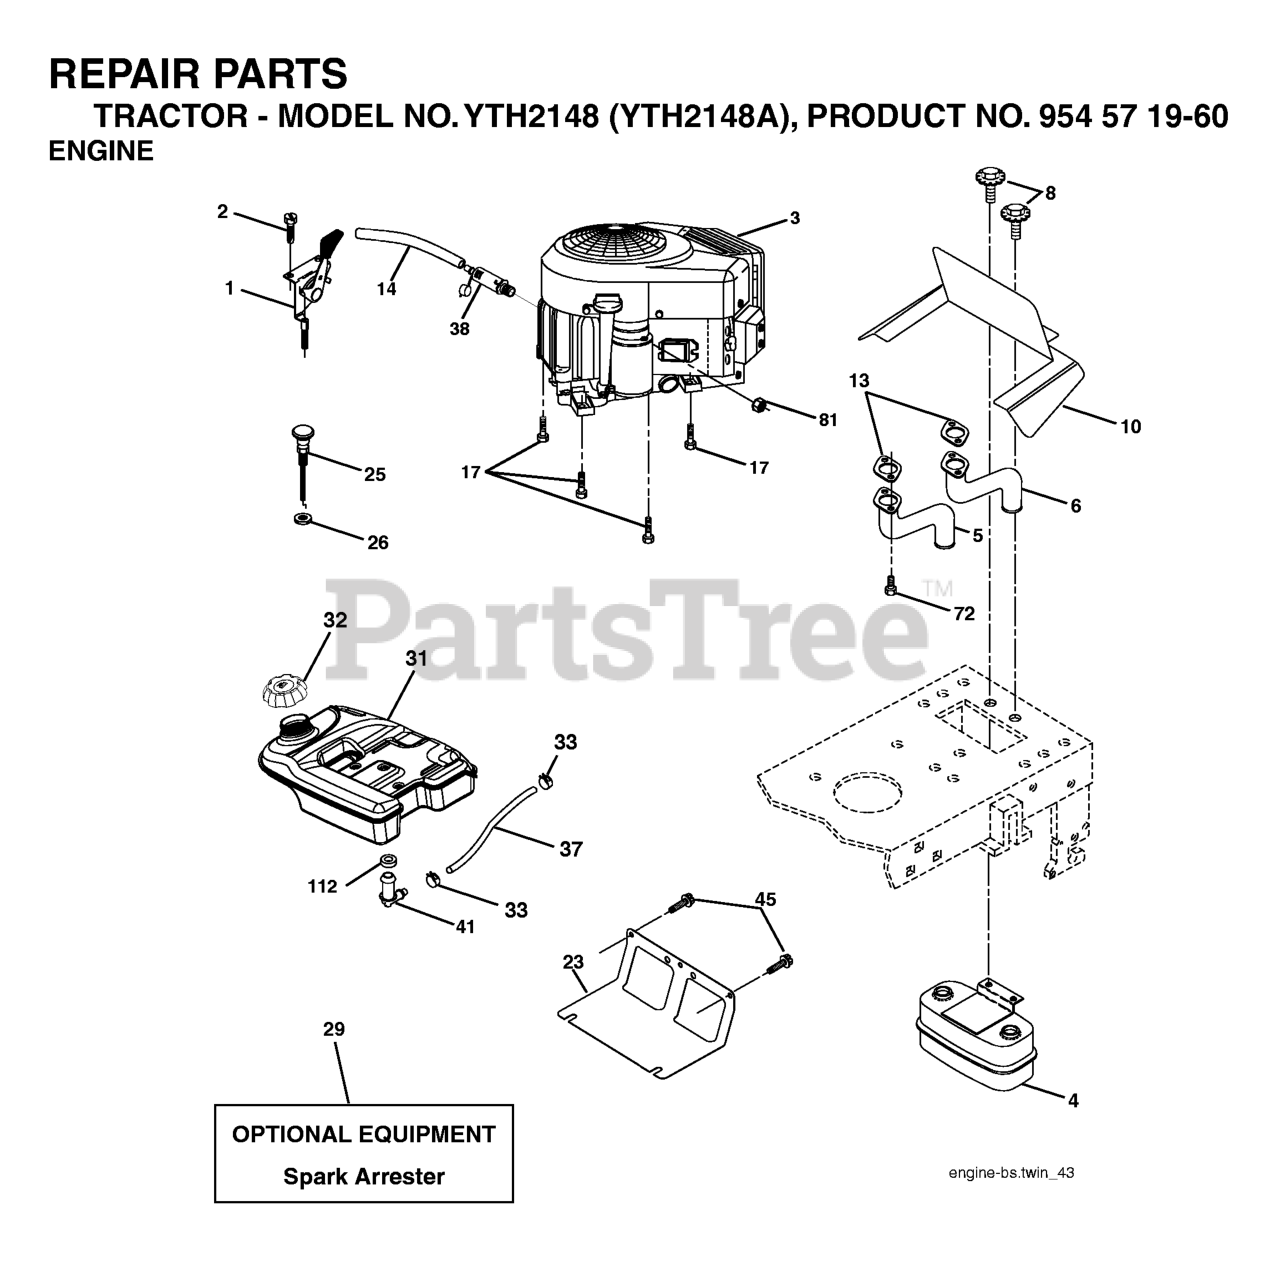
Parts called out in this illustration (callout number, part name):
1	THROTTLE CONTROL
2	SCREW
4	MUFFLER.TWIN.CYL.LOW.TONE
5	RP.EXHAUST.TUBE.LH.BS/TWIN
6	EXHAUST.TUBE.RH.BS/TWIN
8	BOLT.5/16-18UNCX3/4 W/SEMS.BLK
10	SHIELD.BROWNING.B&S
13	GASKET.MUFFLER
14	TUBE, DRAIN OIL ASM.
17	SCREW 3/8-16 X 1-1/2
23	SHIELD.BROWNING.DBR.GUARD
25	CHOKE CONTROL
26	Nut Keps 3/8 - 24 UNF
29	KIT.SPARK ARRESTOR 794945 B&S
31	4.0 REAR FUEL TANK
32	TANK CAP
33	HOSE CLAMP
37	REPL BY 532 00 85-43
38	PLUG DRAIN OIL EASY
41	STEM FUEL TANK
45	SCREW, 3/8-16X3/4
72	SCREW.SOCKET.HEAD.5/16-18
81	NUT
112	BUSHING OUTLET T
